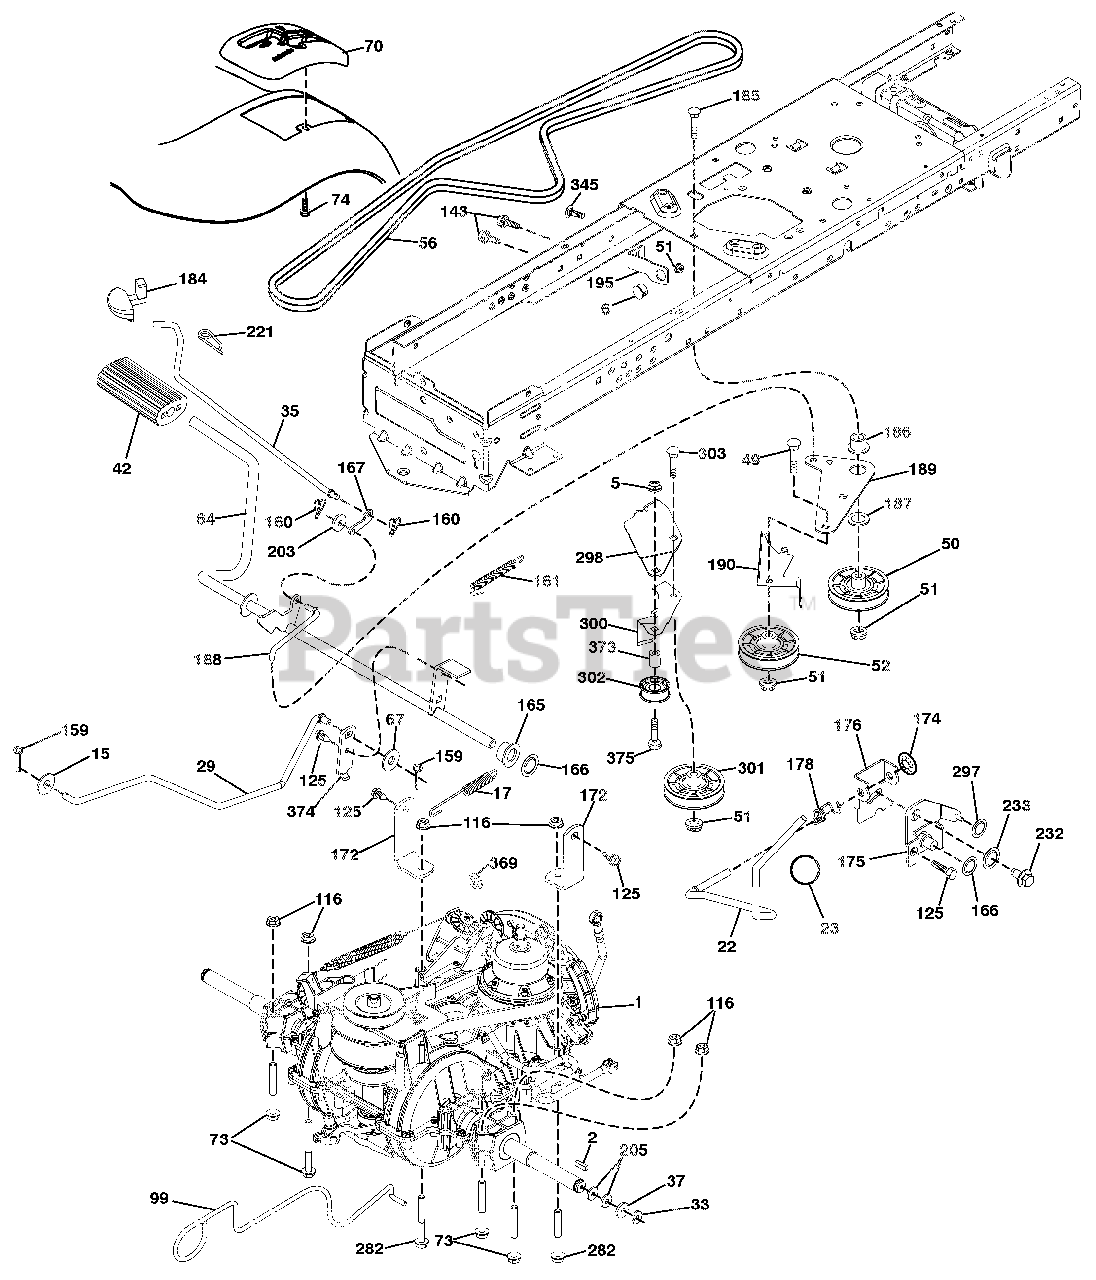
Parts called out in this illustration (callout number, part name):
1	TRANSMISSION, GENTRANS (580486301)(ORDER PARTS FROM TRANSAXLE MANUFACTURER.)
2	KEY.SQUARE.2.0 X .1845/.1865
5	Nut, Hex, Crownlock 3/8-16
6	Bushing Snap Nyl Blk Fuel Line
15	WASHER.13/32 X 13/16 X 16 GA.
17	SPRING.BRAKE.K46.GREEN
22	Rod Shift
29	ROD.BRAKE
33	E-RING.#5133-75
35	ROD, BRAKE, PARK
37	WASHER.HARDEN..793 X 1.637X060
42	COVER PEDAL BLK ROUND
49	Decal, Hand Placement
50	IDLER.FLAT.910"OFFSET
51	Nut, Hex, Flangelock 3/8-16
52	IDLER.V-GROOVE.910"OFFSET
56	BELT.DRIVE.100.97"
64	SHAFT.ASM.BRAKE.CONTROL
67	Washer 13/32 x 13/16 x 12 Ga.
70	CONSOLE
73	BOLT.HEX.FLGHD.5/16-18.GR.5
74	SCREW.HEX.WSH.HI-LO.1/4X1/2UNC
99	ROD.BYPASS
116	Nut, Lock Hex Flange 5/16-18 u
125	SCREW.5/16-18X3/4.SMGML.TAP/BL
143	SCREW.THDROL.5/16-18 X 1/2TYTT
159	PIN.COTTER.1/8 X 3/4.CAD.
160	RETAINER.CLIP(M).DIA.290
161	SPRING.RETURN.CLUTCH.6.75
165	BUSHING.SHAFT.BRAKE.HAND CONTR
166	NUT PUSH .625
167	LATCH.BRAKE.PARKING
172	STRAP TORQUE VARIATOR
174	NUT.PUSH..500
175	Shaft Asm Shift
176	ARM.CLEVIS.ROD.SHIFT
178	SPRING.SHIFT.GT.2006
184	HANDLE PARKING BRAKE
185	BOLT.RDHD.3/8-16UNC X2-3/4 GR5
186	SPACER.RETAINER
187	WASHER.13/32 X 2 X 10 GA.
188	LINK.CLUTCH.GROUND DRIVE
189	BELLCRANK.GROUNDRIVE.NSTG/NSTL
190	KEEPER.BELLCRANK.DRIVE.GROUND
195	BRACKET.BRAKE
203	Washer 11/32 x 11/16 x 16 Ga.
205	WASHER.25/32 X 1-5/8 X 16GA.
221	RETAINER.SPRING.CLIP.HANDLE
232	BOLT.FIN HEX.7/16-14X1 GR5
233	WASHER.SERRATED
282	BOLT.HEX. 5/16-18 X 3 GR. 5
297	Nut Push 1/4
299	Bracket Mount Idler
300	Keeper Idler Rear
301	Pulley Idler V-Groove
302	PULLEY,IDLER.FLAT
303	Bolt Rdhd Sgnk 3/8-16 x 2-1/4
345	Bolt Rdhd Sht Sqnk 3/8-16 x 3/
373	SPACER.IDLER
374	ARM.BRAKE.CONTROL
375	BOLT.HEX.HS.3/8-16.UNCX2-1/4
